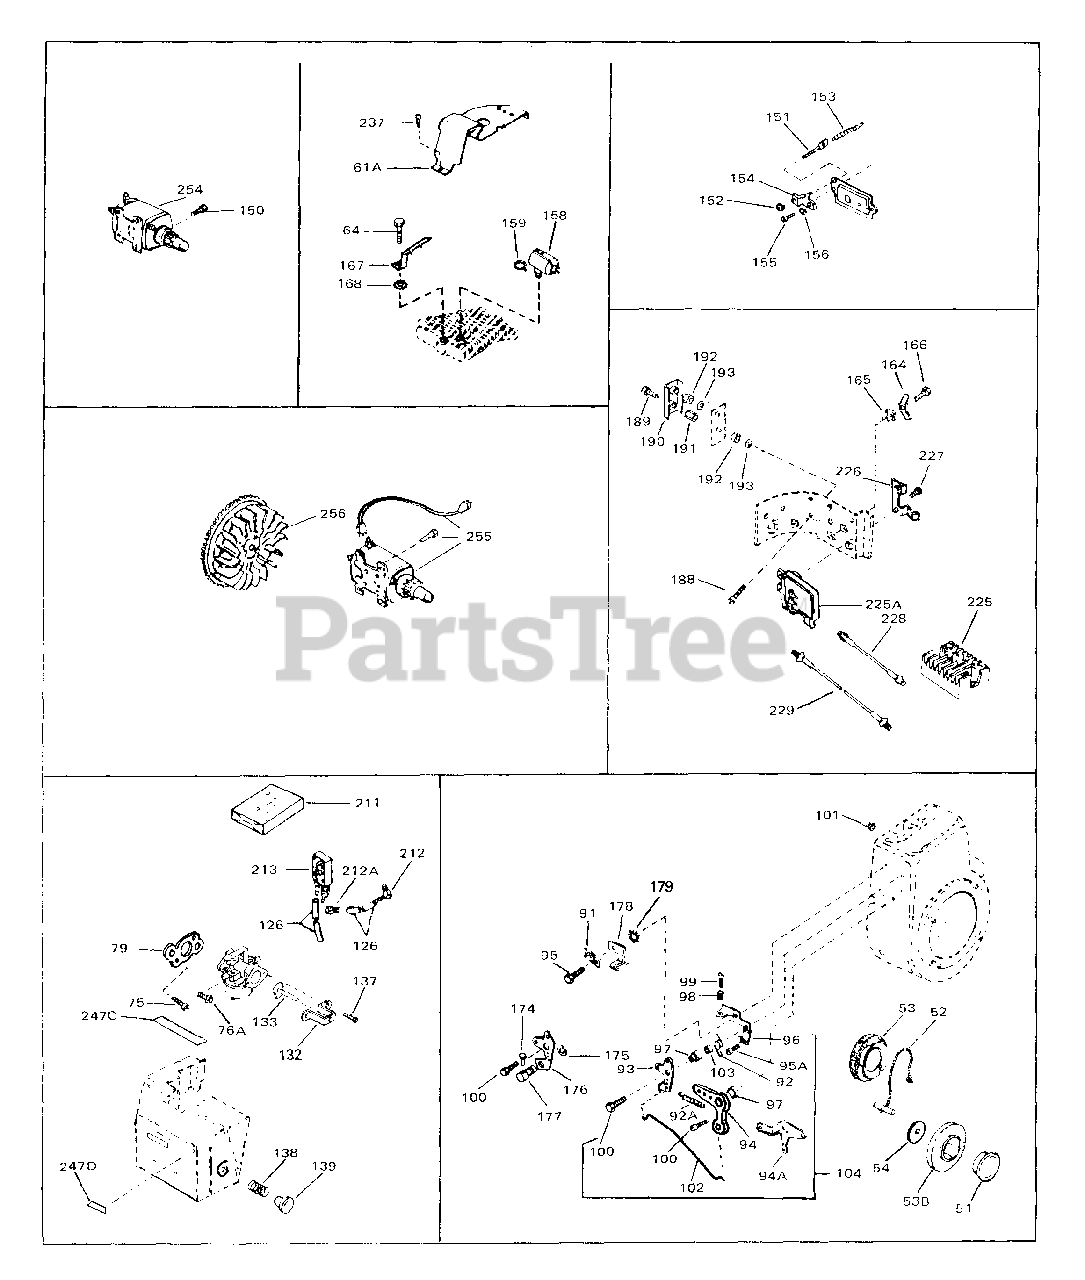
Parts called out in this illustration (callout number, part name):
64	Screw, Hex washer hd. taptite, 1/4-20 x 1/2
91	Clip, Conduit
126	Line, Fuel (Braided 8-1/4")
126	Line, Fuel (Braided 16")
126	Line, Fuel (Braided 32")
132	Bracket, Choke
133	Plate Assy., Choke
137	Screw
138	Spring, Compression
139	Knob, Choke
247C	Decal, Choke & Instruction
247D	Decal, Speed control
255	Starter Motor Kit (110-120 Volt)
256	Flywheel
